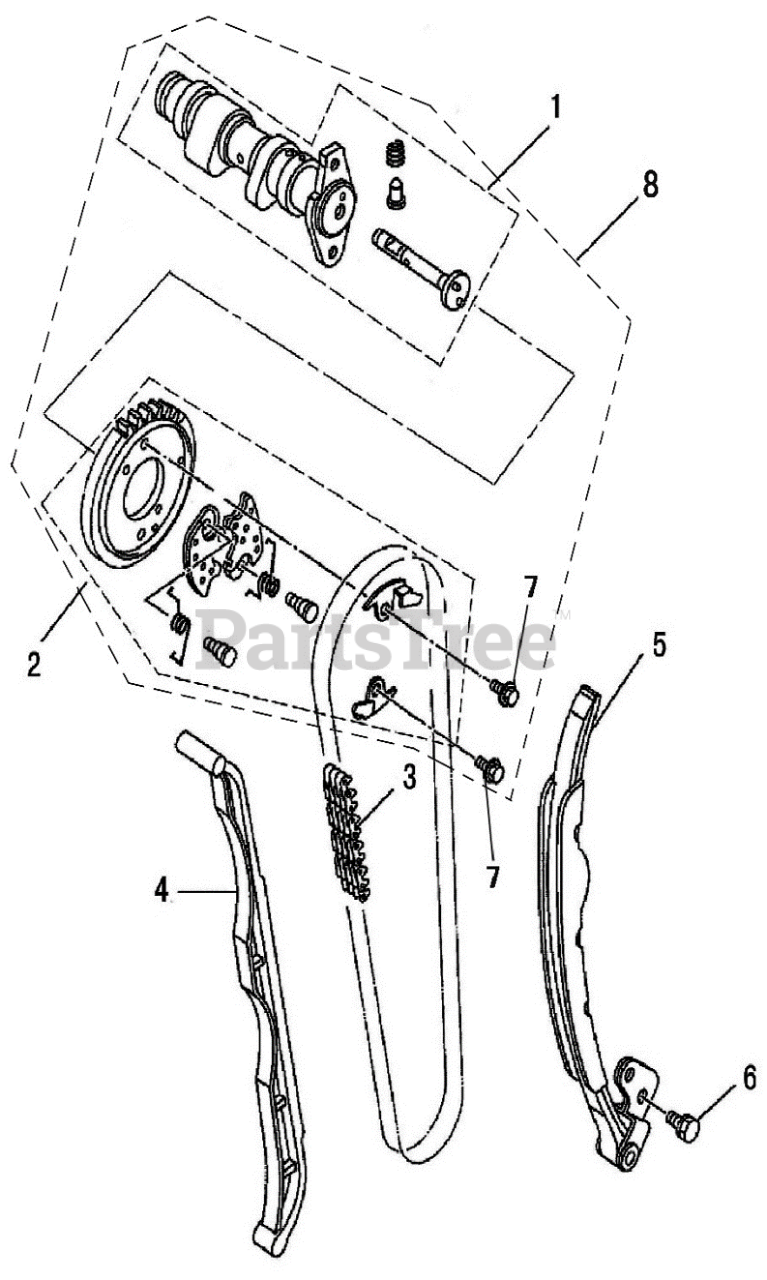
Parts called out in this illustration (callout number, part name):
1	CAMSHAFT ASSEMBLY
2	TIMING DRIVEN SPROCKET ASM
3	TIMING CHAIN M7-6.35-130
4	GUIDE PLATE
5	TENSIONER PLATE
6	HEX HEAD BOLT & PLAIN WASHER
7	HEX FLANGE BOLTS M7X11
8	CAMSHAFT ASSEMBLY
